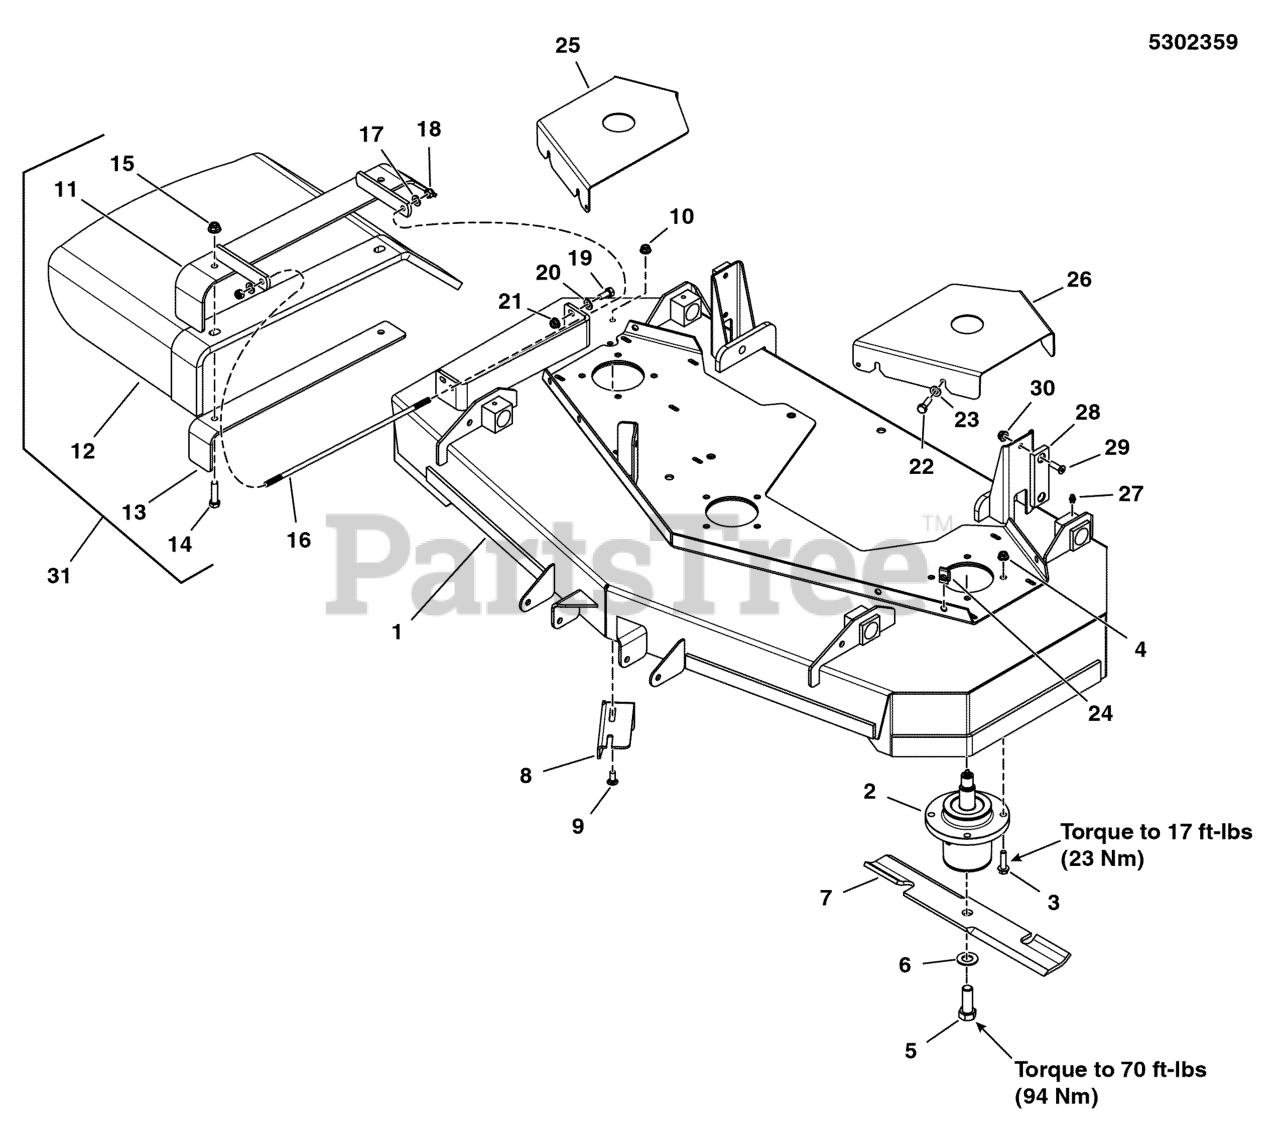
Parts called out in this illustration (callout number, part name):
1	DECK SHELL W/ DECALS, SW30 1848
2	ASSM, SPINDLE, LOW PROFILE
3	BOLT, 5/16-18 X 1 1/4 FLANGE
4	NUT, 5/16-18 HEX NYLOCK FLANGE
5	BOLT, 5/8-11 X 1-3/4 GD8
6	WASHER, 5/8 GRADE 8, YZ
7	BLADES, SET OF THREE (3); 16.25 X.25 X 2.5, 1 X 3.5
8	PLATE, DEFLECTOR - BLK
9	BOLT, 5/16-18 X 3/4, CARRIAGE
10	NUT, 5/16-18 HEX NYLOCK FLANGE
11	WELD, MOUNT, DISCHARGE CHUTE - BLK
12	CHUTE, DISCHARGE, BEND RUBBER, 44/48/52
13	SUPPORT,DISCHARGE CHUTE - BLK
14	BOLT, 3/8-16 X 1-1/2" GD5 CZ
15	NUT, 3/8-16 HEX NYLOCK FLANGE
16	ROD, 5/16 X 13.75, TBE, CZ
17	WASHER, 5/16" SAE
18	NUT, 5/16-24 HEX NYLON LOCK
19	BOLT, 5/16-18 X 3/4 GD5
20	WASHER, 5/16" SAE
21	NUT, 5/16-18 HEX NYLOCK FLANGE
22	BOLT, 5/16-18 X 1 GD5 YZ
23	WASHER, 5/16" SAE
24	BODY CLIP, 5/16-18-7GA MATERIAL
25	GUARD, DECK, 48, SW30, RH - RED
26	GUARD, DECK, 48 - SNP PRO DDS - LH - RED
27	GREASE FITTING, 1/4-28 STRAIGHT
28	PAD, FRICTION, .375 X 1.25 X 4.00
29	SCREW, 5/16-18 X 1, PHILLIPS HD, BZ
30	NUT, 5/16-18 HEX NYLOCK FLANGE
31	KIT, DISCHARGE CHUTE, 44/48/52
